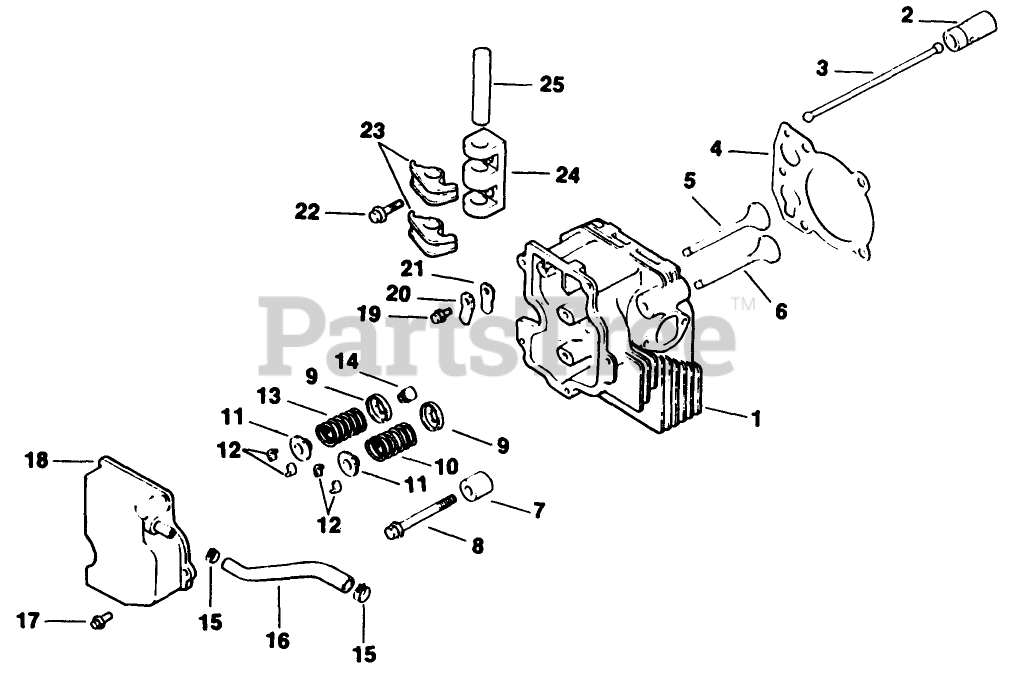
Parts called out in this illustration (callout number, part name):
1	Cylinder Head
2	Lifter-Valve
3	Shaft-Governor Cross (Only On: 72042, 72063, 72062, 72043)
4	Gasket-Cylinder Head
5	Valve-Intake STD (Only On: 72042, 72063, 72062, 72043)
6	Valve-Exhaust STD (Only On: 72042,72043,72062,72063)
7	Spacer-Head Bolt Exhaust (Only On: 72042, 72063, 72062, 72043)
8	Screw M10x1.5x80 (Only On: 72042, 72063, 72062, 72043)
9	Retainer-Spring
10	Spring-Valve Intake (Only On: 72042, 72063, 72062, 72043)
11	Cap-Valve Spring
12	Kit-Retainer
13	Spring-Valve Exhaust (Only On: 72042,72043,72062,72063)
14	Seal
15	Clamp
16	Hose-Breather (Only On: 72042, 72063, 72062, 72043)
18	Cover-Valve W/Nipple (Only On: 72042, 72063, 72062, 72043)
20	Retainer-Reed
23	Arm-Rocker
24	Bridge-Rocker Arm
25	Shaft-Rocker Arm
26	Washer-Flat (Only On: 72042, 72063, 72062, 72043)
